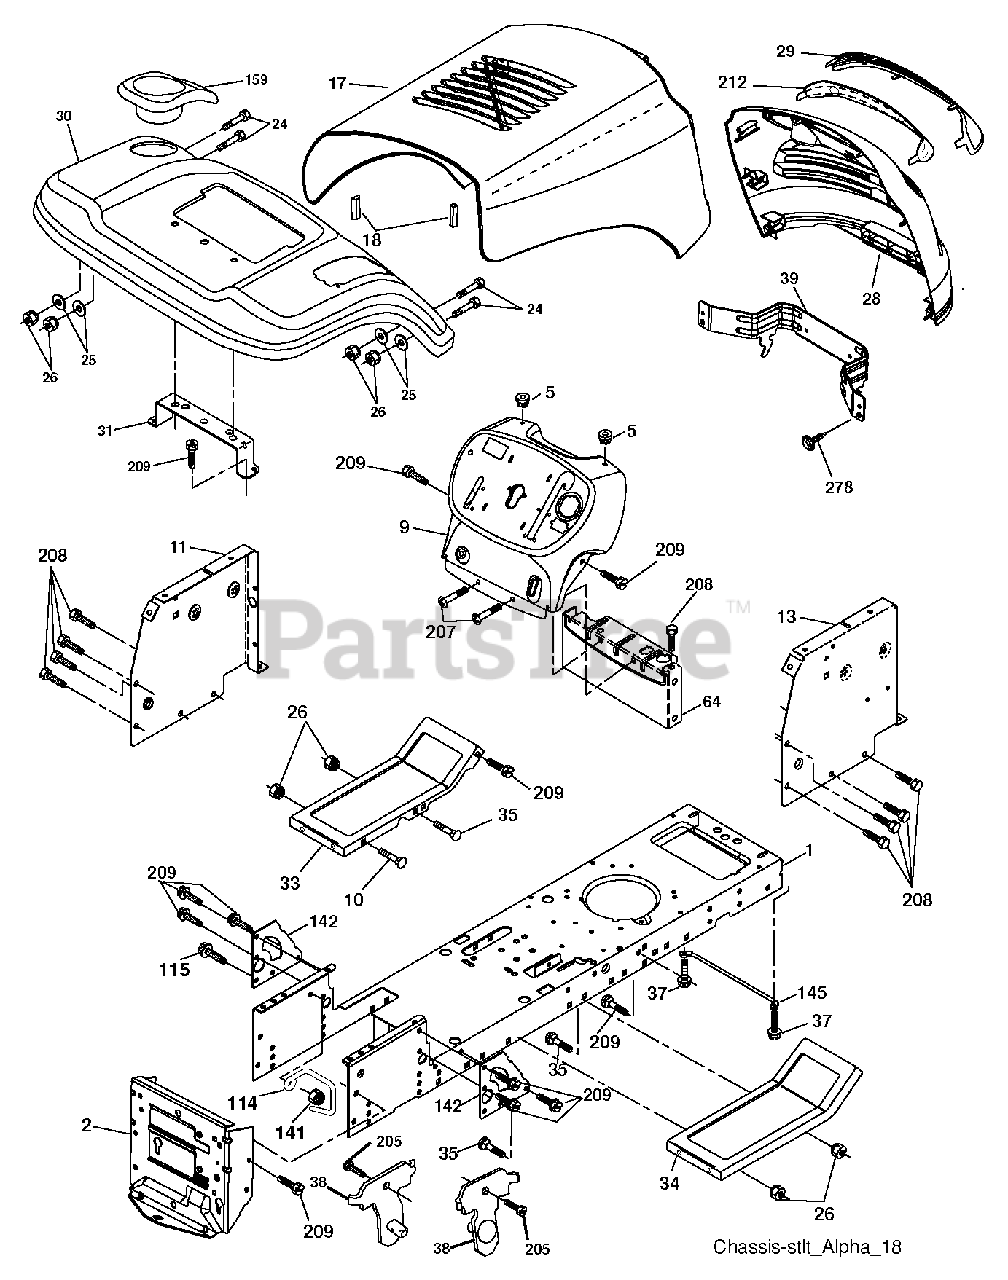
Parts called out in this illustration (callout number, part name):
1	CHASSIS STAMPING
2	DRAWBAR, 12GA
5	BUMPER.RUBBER.HOOD
11	PANEL.DASH.LH.LTX
17	HOOD.STEEL.ELITE.YELLOW
18	BUMPER.HOOD.LARGE.1.75"
25	WASHER
26	NUT
28	GRILLE.ELITE.BASIC.LT.BLACK
29	LENS.GRILLE.BASIC.BAR.LT.CLR
30	FENDER.LTST.W/SHFT.CUP.YELLOW
31	BRACKET FENDER
33	FOOTREST.LH.YELLOW
34	FOOTREST.RH.YELLOW
37	SCREW LT
38	BRACKET.ASM.PIVOT.MOWER.REAR
39	BRACKET PIVOT
64	DASH LOWER
115	SCREW.3/8-16
141	NUT LOCK FLG 3/8-16 UNC
142	PLATE REINFORCEMENT
145	ROD.PIVOT.HOOD
159	CUPHOLDER.BLACK
205	SCREW LT
207	SCREW, 5/16-18 X 1/2
208	SCREW 3/8-16X1/2
209	SCREW, 3/8-16X3/4
212	INSERT.LENS.REFLECTIVE.LEFT
278	SCREW.#10 X 0.750.BOS (2 2)
